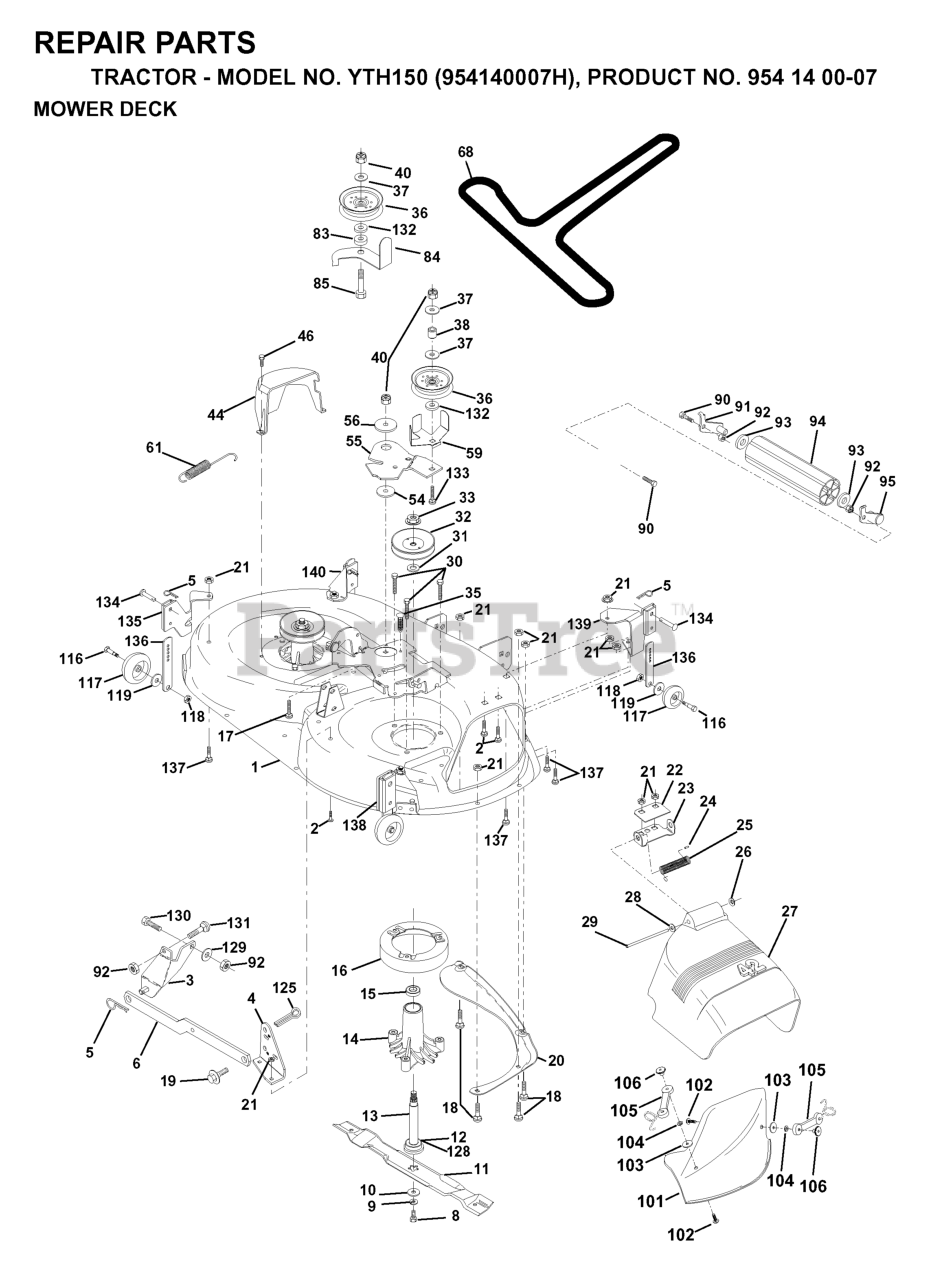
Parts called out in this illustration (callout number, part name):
2	RP BOLT 5/16-18 X3/4 ZN/YEL GR
3	BRKT ASM SWAY BAR
4	BRKT DECK SW BAR
5	RETAINER-SPRNG RB
6	REAR SUSP ARM
8	BLADE BOLT
9	LOCKWASHER
10	WASHER.BLADE
11	BLADE.42".MULCH
12	BEARING.BALL.#6204.(MANDREL)
13	SHAFT ASM VENT
14	HOUSING.MANDREL.VENTED (MACHD)
16	STRIPPER
17	BOLT CARRIAGE
18	BOLT
19	BOLT SHD 5/16-18
20	BAFFLE.VORTEX
21	LOCKNUT
22	STIFFENER BRACKET
23	DEFLECTOR BRACKET
24	CAP-SLEEVE LT
25	SPRING TORSION
26	NUT PUSH M
27	SHIELD.DEFLECTOR.MOWER.42".BLK
28	Washer 11/32 x 5/8 x 16 Ga SD
29	ROD.HINGE
30	SCREW THDROL ROLLING WASHER HD
31	WASHER
32	PULLEY/MANDREL
33	NUT
35	FASTENER.XMAS.TREE
36	FLAT IDLER PULLEY
37	WASHER
38	IDLER SPRING SPACER
44	GUARD MANDREL LH BLACK
46	SCREW.1/4-20X5/8
54	HARDENED WASHER
55	IDLER ARM
56	SPACER RETAINER
59	GUARD, BELT
61	SPRING EXTENSION
68	V-BELT TRIPATH
84	KEEPER.BELT.IDLER
90	BOLT
91	BRACKET LH (A)
92	NUT
93	Washer 1 17/32 X 7/8 X 16 Ga
94	NOSE ROLLER
95	BRACKET RH (B)
101	COVER MULCH 42"
102	SCREW
104	LOCKWASHER #10
105	LATCH ASSY
106	WELDNUT
116	BOLT, SHOULDER
117	WHEEL GAGE DONUT
118	LOCKNUT
119	WASHER.5/16.FLAT.STE.STD.
125	Pin Cotter 1/4 x 1 Plated
128	WASHER FELT
129	WASHER
131	BOLT D
132	Washer 13/32 x 1-3/8 x 13 Ga.
134	RIVET.PIN.HEAD.YELLOW.
135	BRACKET ASSY
136	BAR.ADJUST.WHEEL.ANTI.SCALP.BL
137	BOLT.CARR.5/16-18X5/8.SHORT
138	GAUGE WHEEL BRACKET ASSY
139	BRACKET.WHEEL.GAUGE.FRONT.42
140	BRKT.ASM.WHL.GA.FRONT.LH
